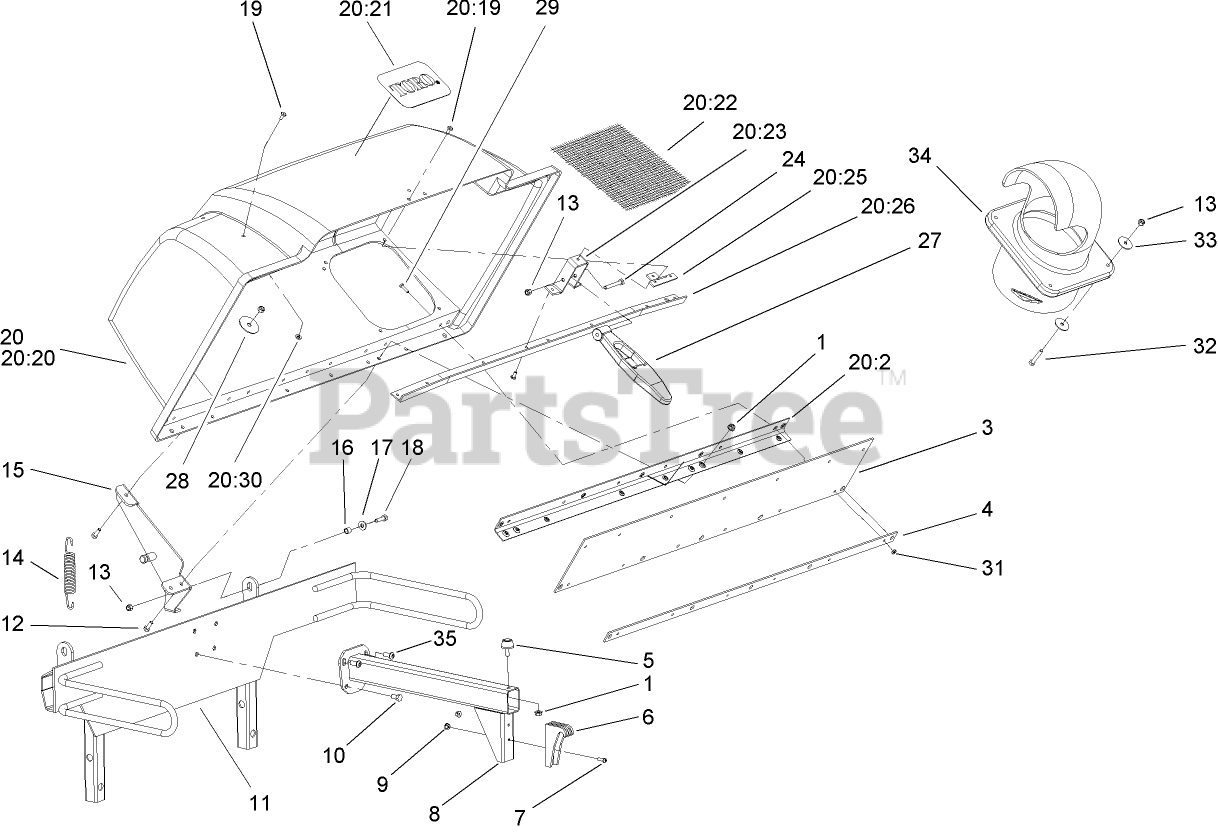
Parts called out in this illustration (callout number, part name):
1	NUT-HF
4	PLATE-BACKING
5	BUMPER
7	SCREW-PPH
8	SUPPORT-BAG
9	NUT-HF
10	SCREW-HH
11	BAGGER UPRIGHT ASM
12	SCREW-HH
13	NUT-LOCK, NI
14	SPRING-EXTENSION
15	HINGE ASM
16	SPACER
17	WASHER-FLAT
18	SCREW-HH
19	RIVET-BLIND
20	HOOD ASM
20:2	STIFFENER-BAGGER, TOP
20:19	RIVET-BLIND
20:20	TOP-BAGGER
20:22	SCREEN-BAGGER
20:23	ANCHOR-LATCH
20:25	REINFORCEMENT-LATCH
20:26	SUPPORT-SCREEN
20:30	WASHER-FLAT
24	SCREW-HH
28	WASHER
29	SCREW-HEAD, TRUSS
31	NUT-LOCK, SIDE
32	SCREW-HH
33	WASHER-FLAT
34	ADAPTER-TUBE, UPPER
35	SCREW-HSBH
